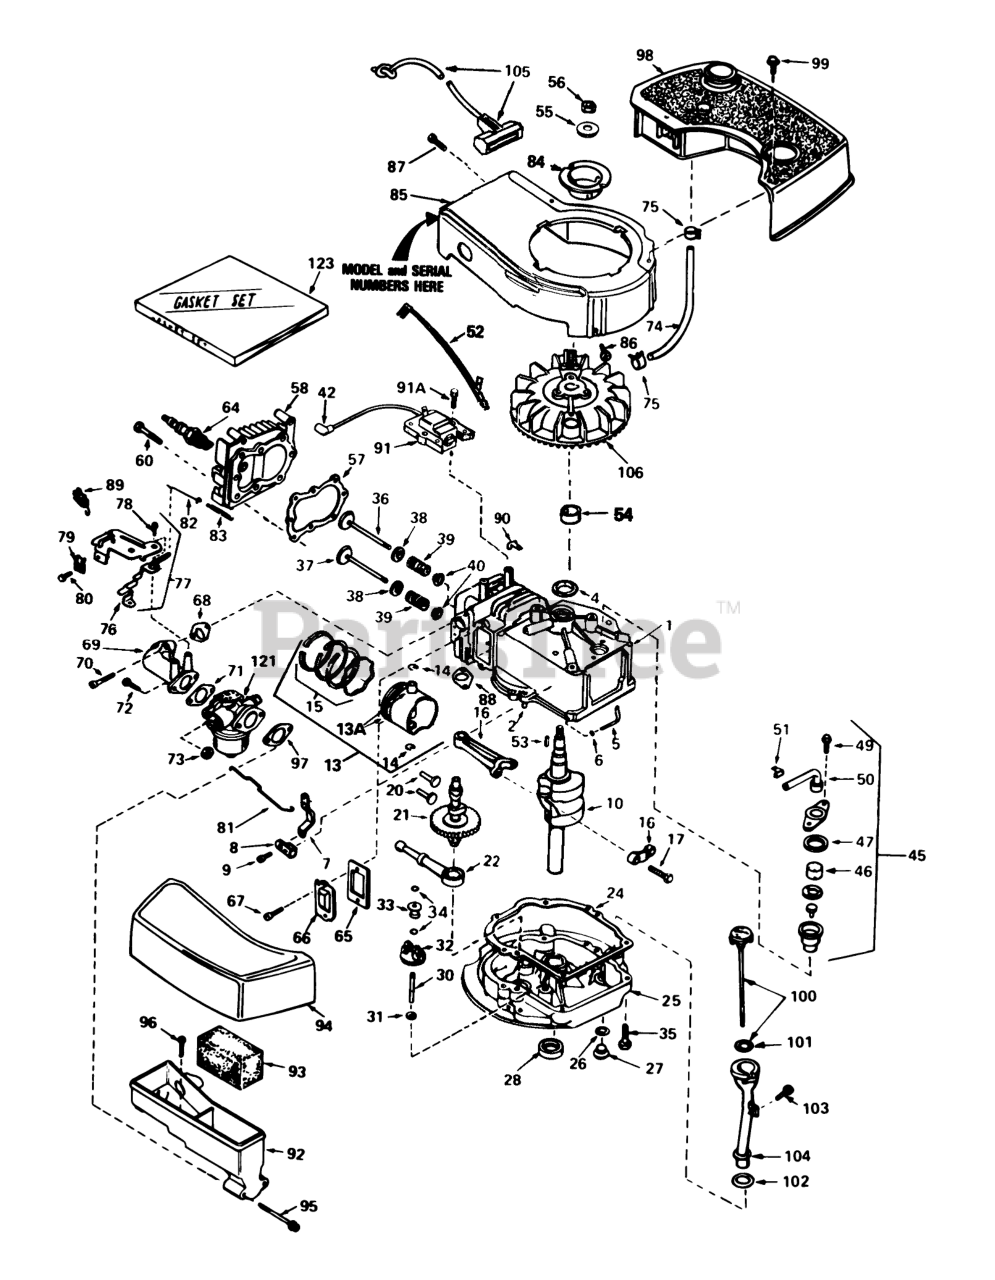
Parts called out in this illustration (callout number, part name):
1	Cylinder Assembly (Incl. Ref. #2 & 4)
2	Pin-Dowel
4	Seal-Oil
5	Rod, Governor (Incl. Ref. #6)
6	Washer-Flat
7	Governor Lever
8	Clamp-Lever, Governor
9	Screw
10	Crankshaft
13	Piston, Pin & Ring Assy. (Std.)(Incl. Ref. #13A, 14 & 15)
13	Piston, Pin & Ring Assy. (.010 O.S.)(Incl. #13A, 14 & 15)
13	Piston, Pin & Ring Assy. (.020 O.S.)(Incl. #13A, 14 & 15)
13A	Piston & Pin Assy. (Std.)(Incl. Ref. #14)
13A	Piston & Pin Assy. (.010 O.S. (Incl. Ref. #14)
13A	Piston & Pin Assy. (.020 O.S.)(Incl. Ref. #14)
14	Ring-Retaining, Piston Pin
15	Ring Set (Std.)
15	Ring Set (.020" OS)
15	Ring Set (.010" OS)
16	Rod Assy., Connecting (Incl. Ref. #17)
17	Bolt-Rod, Connecting
20	Lifter-Valve
21	Camshaft(Mech.Comp. Release)
22	Oil Pump ASM
24	Gasket, Mounting
25	Flange Assy., Mounting (Incl. Ref. #26 thru 30)
26	Gasket-Oil Drain
27	Plug Oil Drain
28	Seal Oil
30	Shaft-Governor
31	Washer-Flat
32	Gear Assy., Governor (Incl. Ref. #31 )
33	Spool-Governor
34	Ring-Retaining
35	Screw (1/4-20 x 1-1/4)
36	Valve, Intake (Std.)(Incl. Ref. #40)
36	Valve, Intake (1/32" O.S.)(Incl. Ref. #40)
37	Valve, Exhaust (Std.)(Incl. Ref. #40)
37	Valve, Exhaust (1/32" O.S.)(Incl. Ref. #40)
38	Cap-Upper Valve Spring
39	Spring-Valve
40	Cap-Valve, Spring
42	Cover-Spark Plug
45	Breather Assy. (Incl. #46-51)
46	Element-Breather
47	Gasket-Breather
49	Screw (10-24 x 9/16)
50	Tube, Breaker
51	Clip, Breather
52	Wire-Ground
53	Key-Flywheel
55	Washer-Belleville
56	Nut-Flywheel
57	63573 GIL 42 SNWTHW
58	Head-Cylinder
60	Screw (5/16-18x1-1/2)
64	Plug, Spark (J17LM or equiv.)
64	Plug, Spark (Champion RCJ-8)
65	Gasket-Breather
66	Cover-Valve
68	Gasket-Intake
69	Pipe, Intake (Incl. Ref. #68)
70	Screw (1/4-20 x 1)
71	Gasket-Carburetor
72	Screw (1/4-28 x 7/8)
73	Nut and Lock Washer (1/4-28)
74	Line-Fuel
75	Clamp-Line, Fuel
76	Lever Control
77	Control Assy., Speed (Incl. Ref. #76, 78 & 89)
78	Screw, Hex Washer Hd Shoulder Self-Tap
79	Conduit
80	Screw (10-32 x 3/8)
81	Link-Throttle
82	Link Governor Spring
83	Spring Governor
84	Hub-Starter
85	Housing Blower
86	Screw (1/4-20x19/32)
87	Screw (10-24 x 9/16)
88	Gasket Exhaust
89	Terminal
90	Clip-Wire
91	Lamination & Coil Assy. (Solid State)(Incl. Ref. #42)
91A	Screw
92	Body Air Cleaner
93	Filer, Air
94	Cove, Air Cleaner
95	Screw Fil Hd.
96	Screw, Hex Hd.
97	Gasket-Air Cleaner
98	Tank-Fuel
99	Screw (10-32 x 35/64)
100	Dipstick, Oil (Incl. Ref. #101)
103	Screw (10-32 x 1/2)
104	Tube-Oil Fill
105	Rope Assy., Starter
106	Flywheel
121	Carburetor (Incl. Ref. #71)
123	Gasket Set
